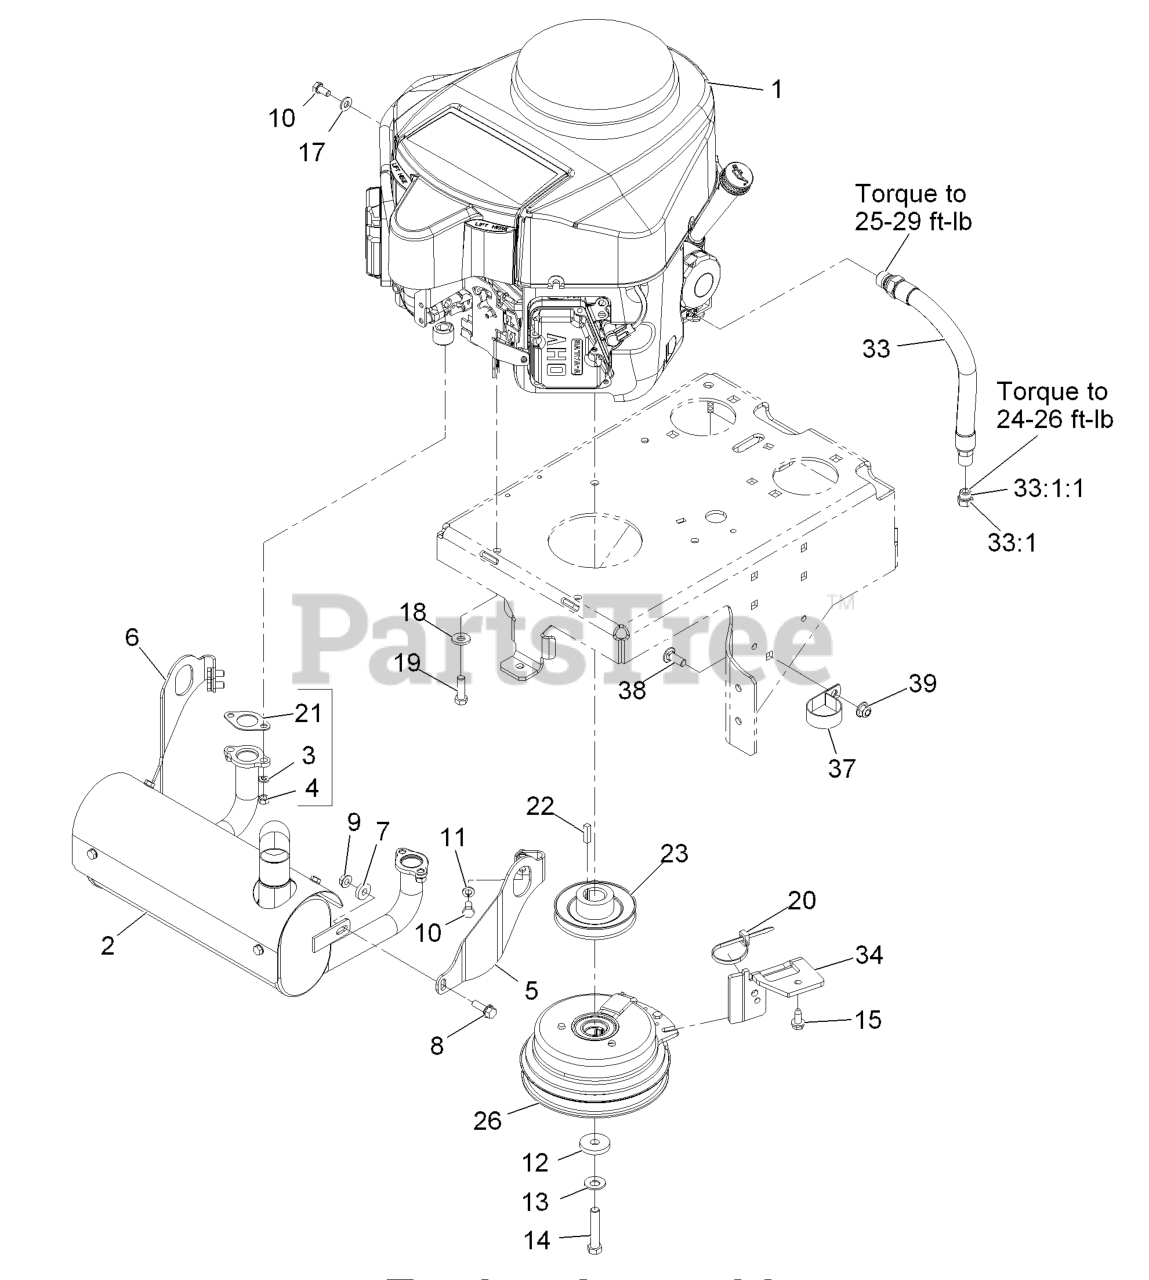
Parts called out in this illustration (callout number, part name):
1	Engine-Kawasaki, Fs691v-As12 (24 Hp)
3	WASHER-LOCK
5	BRACKET-MUFFLER MOUNT, LH
6	BRACKET-MUFFLER MOUNT, RH
8	SCREW-HHF
10	SCREW-HH
11	WASHER-LOCK
12	WASHER
13	WASHER-SPRING
14	SCREW-HH
15	Screw-HWH 5/16-18 X 3/4 Tf
17	WASHER-PLAIN
18	WASHER-BELLEVILLE
19	SCREW-HH
20	TIE-CABLE
21	GASKET-EXHAUST
26	CLUTCH-WARNER
33	ENGINE OIL DRAIN HOSE ASM
33:1	PLUG-HH
33:1:1	O-RING
34	BRACKET-ANCHOR, CLUTCH
37	CLAMP-R
38	SCREW-CARR
39	NUT-HF, NI
